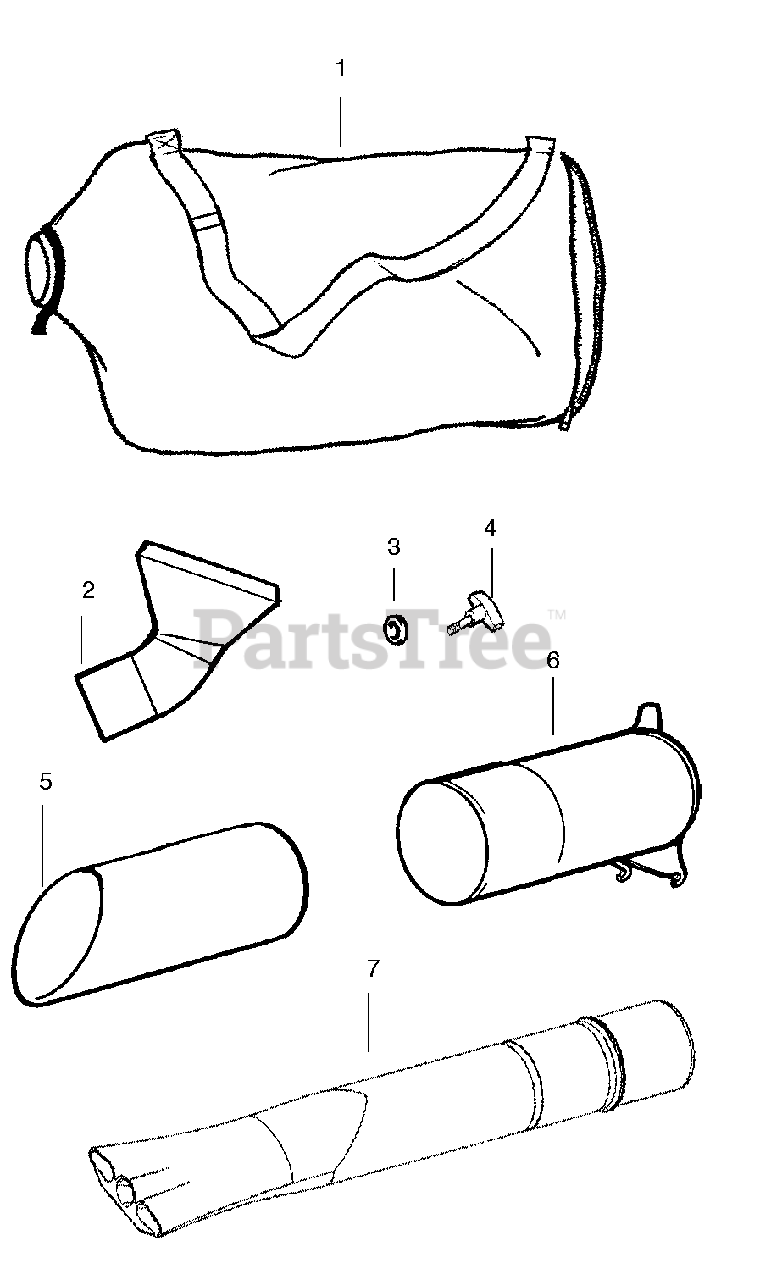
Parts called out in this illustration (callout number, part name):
1	Assy-Vac. Bag w/strap
2	Tube-Elbow Vac
3	Retainer-Vac Tube Knob
5	Tube-Lower Vac
6	Tube-Upper Vac
7	Tube-Blower
